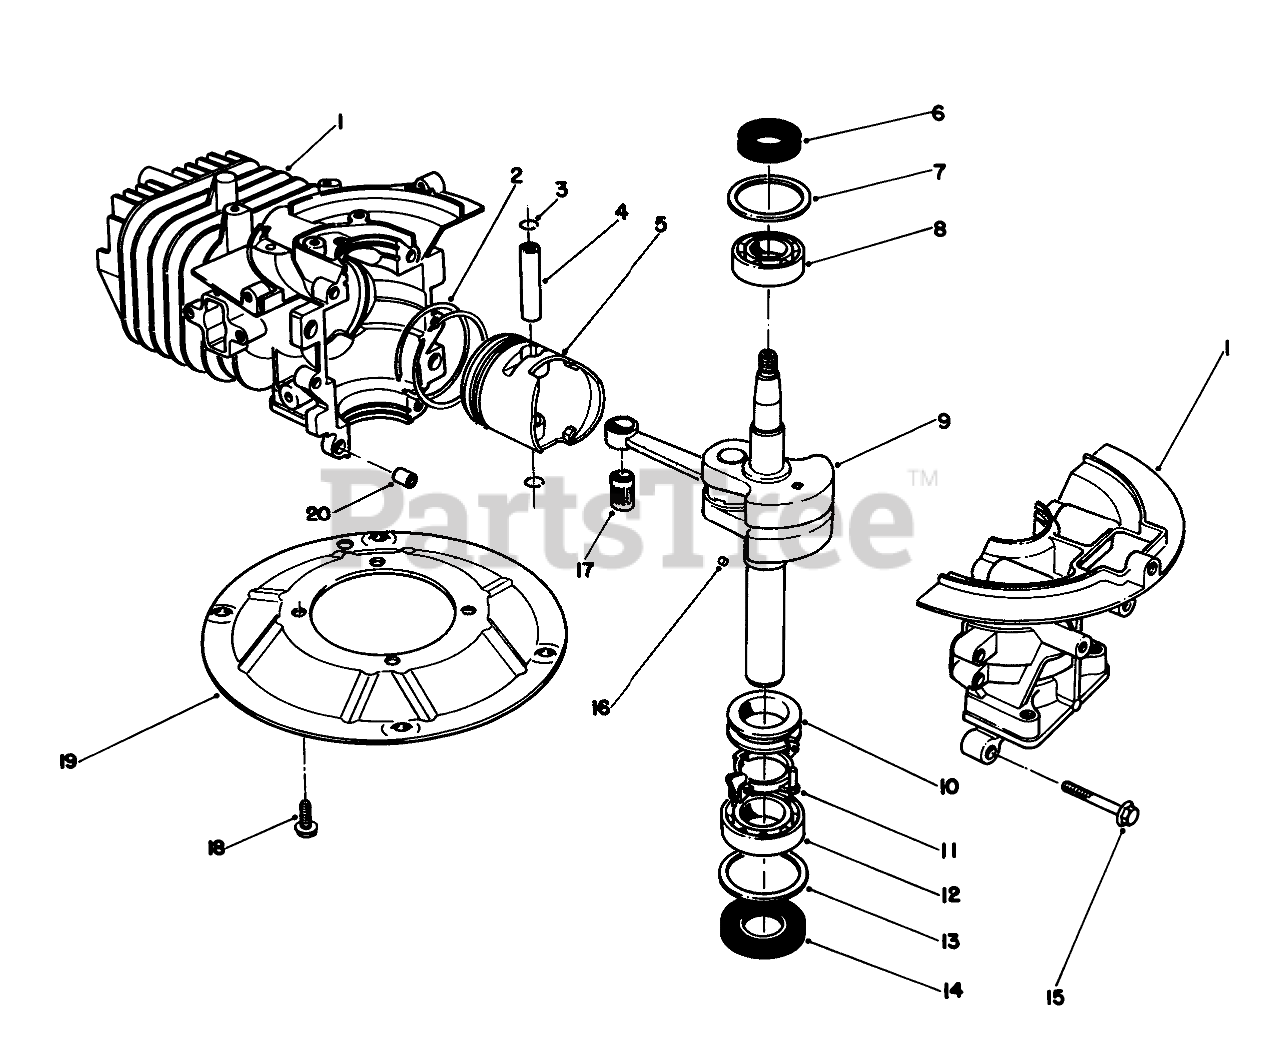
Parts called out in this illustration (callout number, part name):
1	CRANKCASE
2	RING SET
4	PIN-PISTON
5	Piston
6	OIL SEAL
7	WASHER-UPPER
8	BEARING-UPPER
9	Pin-Wrist
10	SPACER
11	BRACKET
12	LOWER BRG
13	WASHER-LOWER
14	SEAL-OIL
17	BEARING
19	PLATE-MOUNTING
